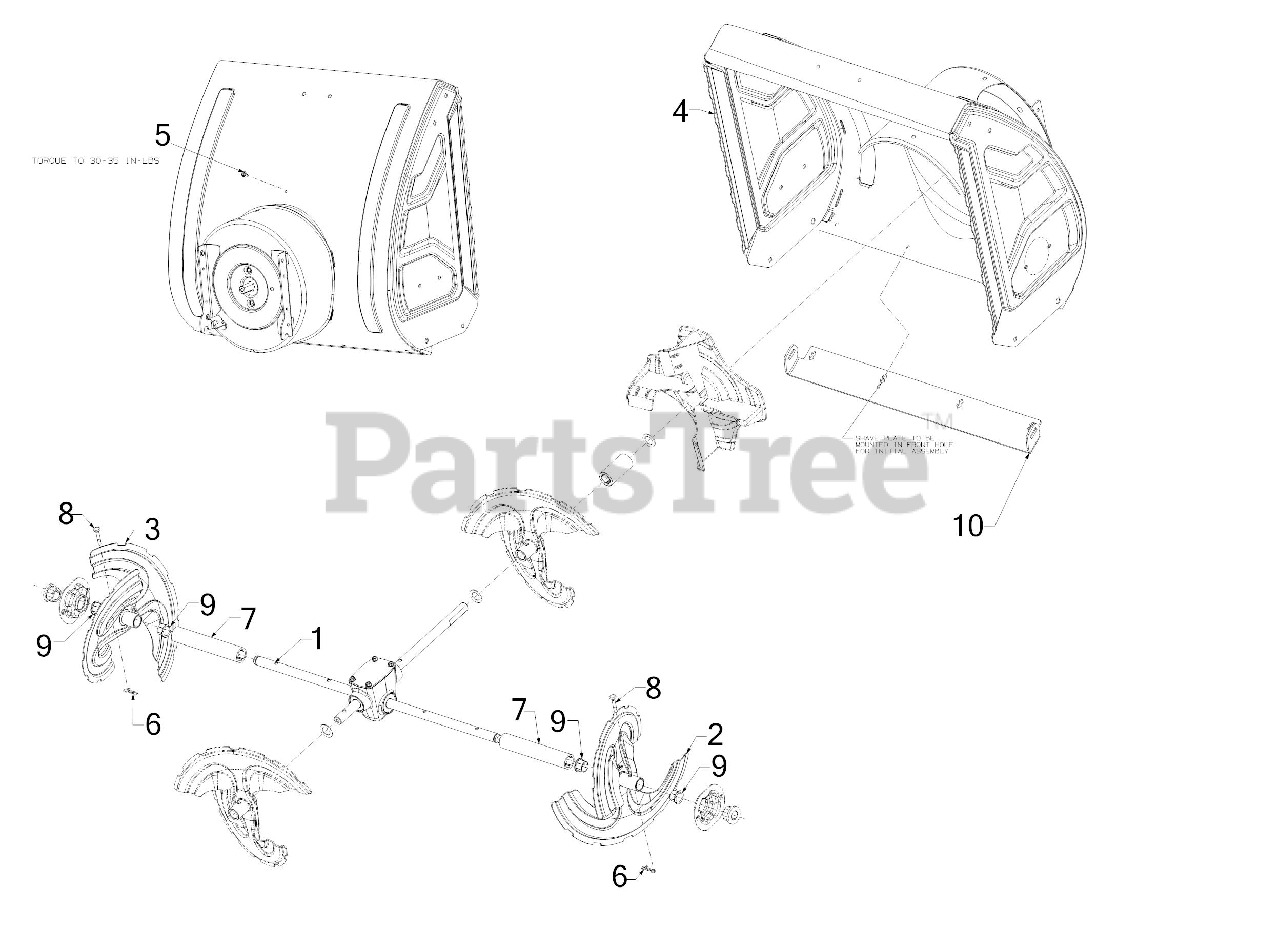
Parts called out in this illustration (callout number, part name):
1	26" AUGER GEARBOX ASSEMBLY
5	SCREW M6-1 x .625
6	BOW TIE COTTER PIN 1/4-5/16
8	SHEAR PIN .25 x 1.50 GR2
9	FLANGE BUSHING
